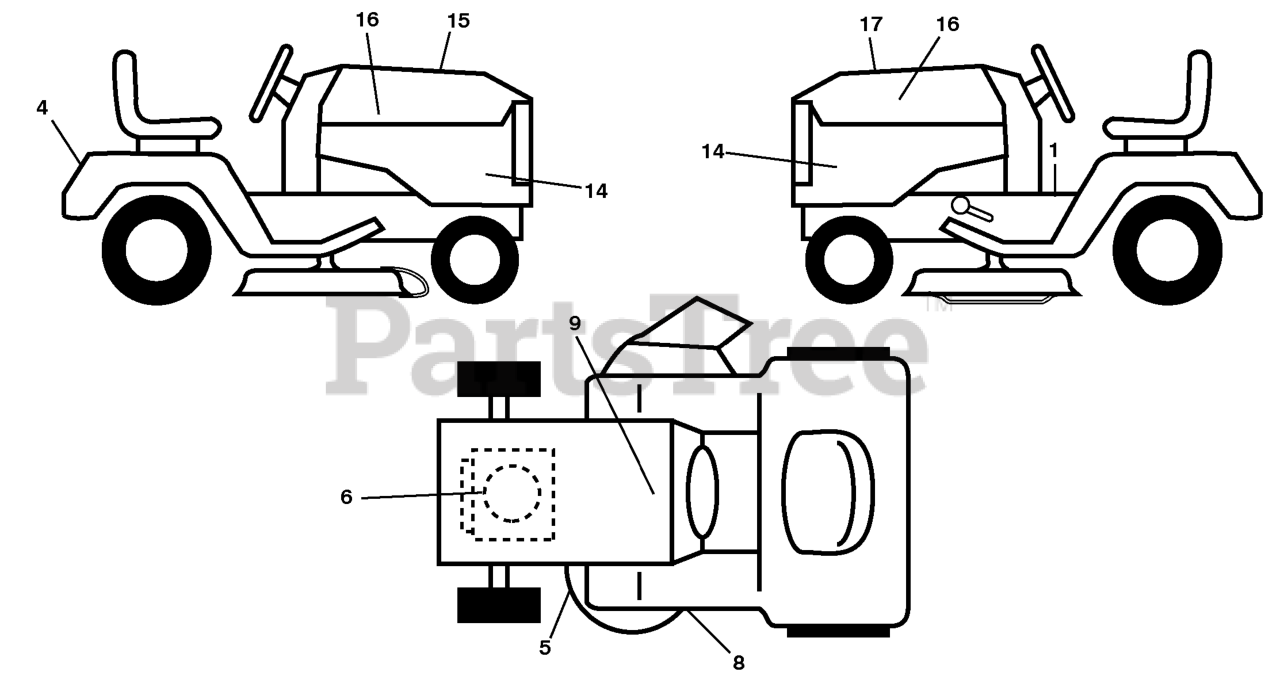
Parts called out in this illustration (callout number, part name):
1	Decal, Operator's
4	Decal, Fender
5	Decal, Caution
6	Decal, Eng. HP
8	Decal, Mower Sch.
9	Decal, Battery Dnge/Poi
14	Decal, Panel Side
15	Decal, Cust. Resp.
16	Decal, Hood Logo
17	Decal, Replacement
